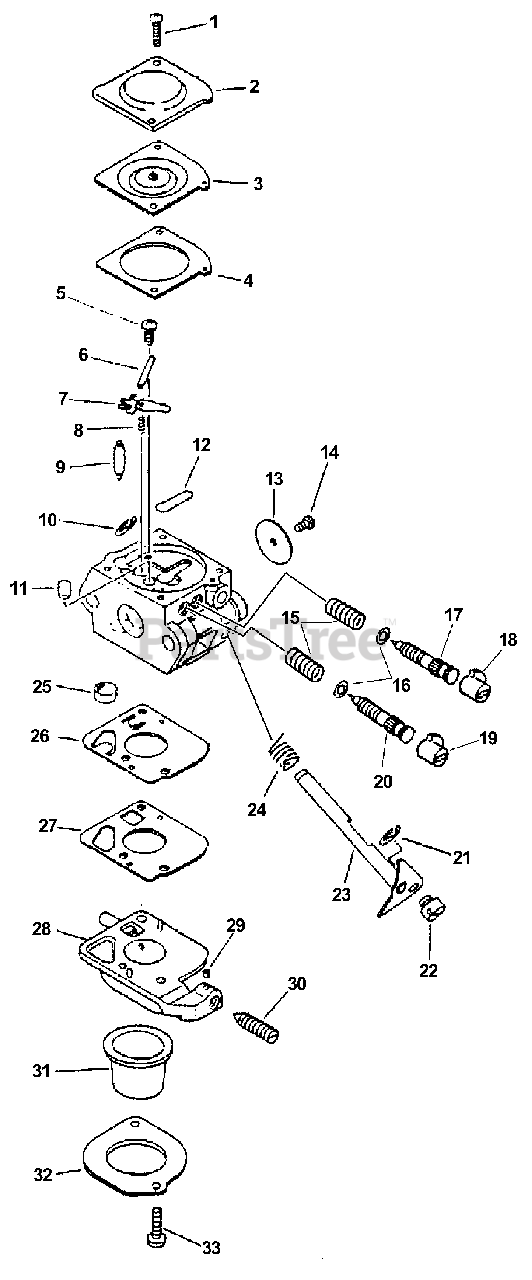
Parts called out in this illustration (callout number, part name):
2	COVER, METERING
3	DIAPHRAGM
4	GASKET, DIAPHRAGM
5	SCREW, METERING LEVER PIN
6	PIN, METERING LEVER
7	LEVER, METERING
8	SPRING
9	VALVE, INLET NEEDLE
10	RING, RETAINING
11	NOZZLE, CHECK VALVE
12	PLUG, WELCH
13	VALVE, THROTTLE
17	NEEDLE - LOW SPEED
18	CAP, LIMITER
19	CAP, LIMITER
20	NEEDLE - HIGH SPEED
21	RING, RETAINING
23	SHAFT, THROTTLE
24	SPRING, RETURN
25	STRAINER
26	DIAPHRAGM, PUMP
27	GASKET, PUMP
28	BASE, PURGE
29	PIECE, FRICTION
30	SCREW, IDLE ADJUST
31	BULB, PURGE
32	RETAINER, PURGE BULB
33	SCREW, RETAINER
